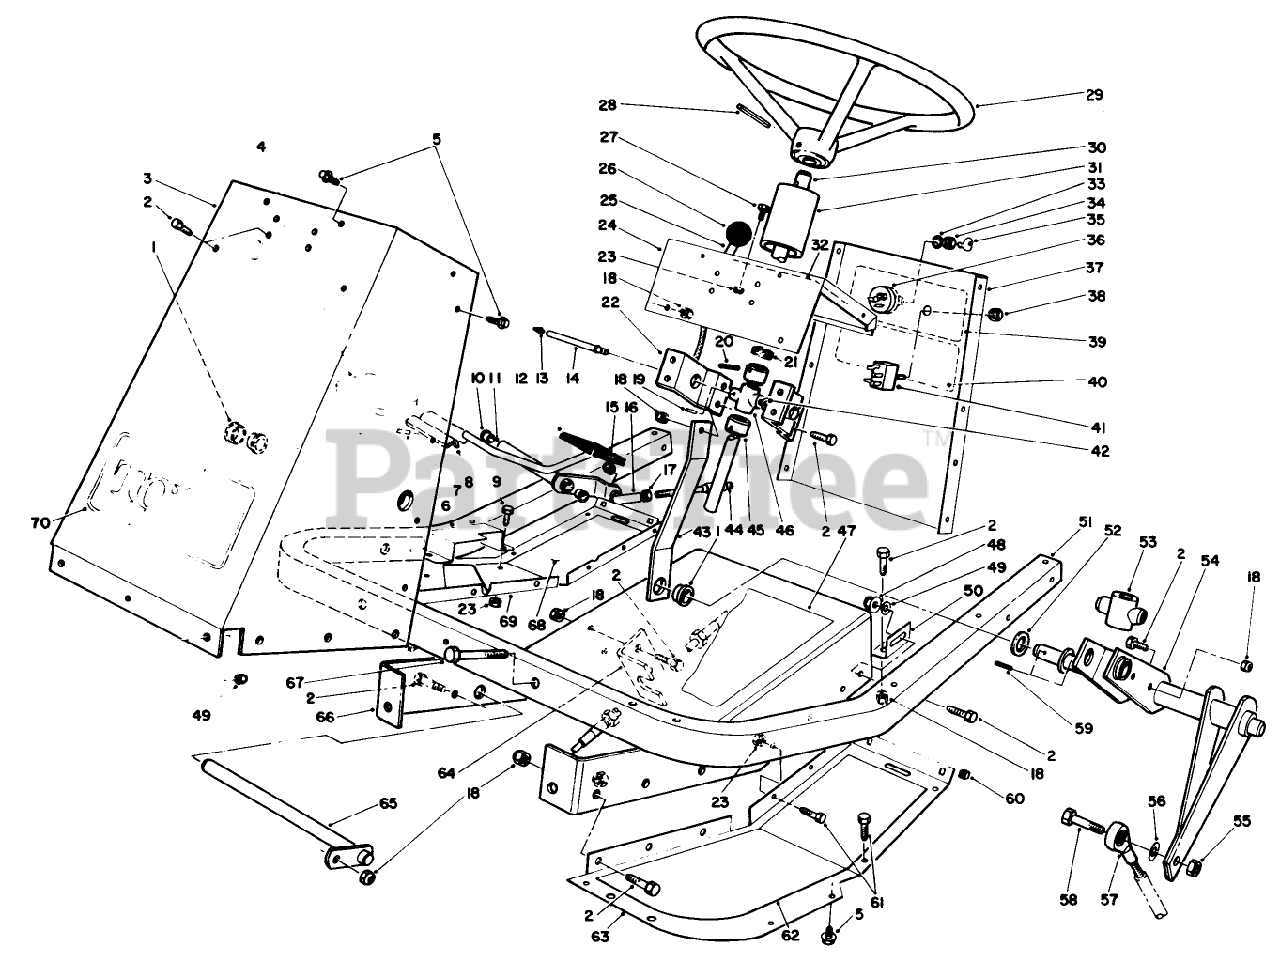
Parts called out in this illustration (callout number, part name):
1	BEARING-FLANGE
2	SCREW-HH
3	Tower-Front
4	FORWARD PEDAL PAD
5	SCREW-HHFTF
6	Footrest-Pedal
7	PIN-SPRING
8	ACCELERATOR PEDAL
9	SCREW-HH
10	BUSHING-FLANGE
11	Traction Pedal (Incl. Ref. #10)
12	REVERSE PAD
13	FITTING-GREASE
14	TUBE ZERK
15	NUT-LOCK
16	JOINT-BALL
17	NUT-JAM
18	NUT-LOCK, NI
19	3/32 X 9/16 ROLL PIN
20	PIN-SPRING
21	COVER-DUST
22	BRG SUPT BRKT
23	NUT-LOCK, NI
24	Tower-Top
25	CONTROL-CHOKE,THROTTLE
27	SCREW-HH
28	PIN-ROLL
29	WHEEL-STEERING
30	STEERING SHAFT
31	STRG. SHAFT COVER
32	THROTTLE DECAL
33	Washer-Lock
34	Nut-Hex
35	KEY-IGNITION
36	Switch-Ignition (Incl. Ref. #33-35)
37	REAR TOWER PANEL R
38	NUT
39	THROTTLE DECAL
40	SWITCH DECAL
41	Switch
42	WASHER-BELLEVILLE
43	Link-Steering
44	TRACT CONT.CABLE
45	STRG SHAFT COLLAR
46	BRG STEERING SHAFT
47	TUNNEL DECAL
48	NUT-HF
49	WASHER-PLAIN
50	TUNNEL BRKT
51	Frame-Footrest
52	WASHER-THRUST
53	STEER.SHAFT FOLLOWER
54	Follower Lever
55	NUT-HEX
56	WASHER-FLAT
57	BALL JOINT LH
58	SCREW-HH
59	PIN-ROLL
60	NUT-RETAINED
61	SCREW-HH
62	FOOT REST PAD LH
63	Footrest-L.H.
64	TRACT CABLE BRKT
65	PEDAL.SHAFT WA
66	Tunnel
67	SCREW-HH
68	FOOTREST PAD
69	Footrest-R.H.
70	DECAL
